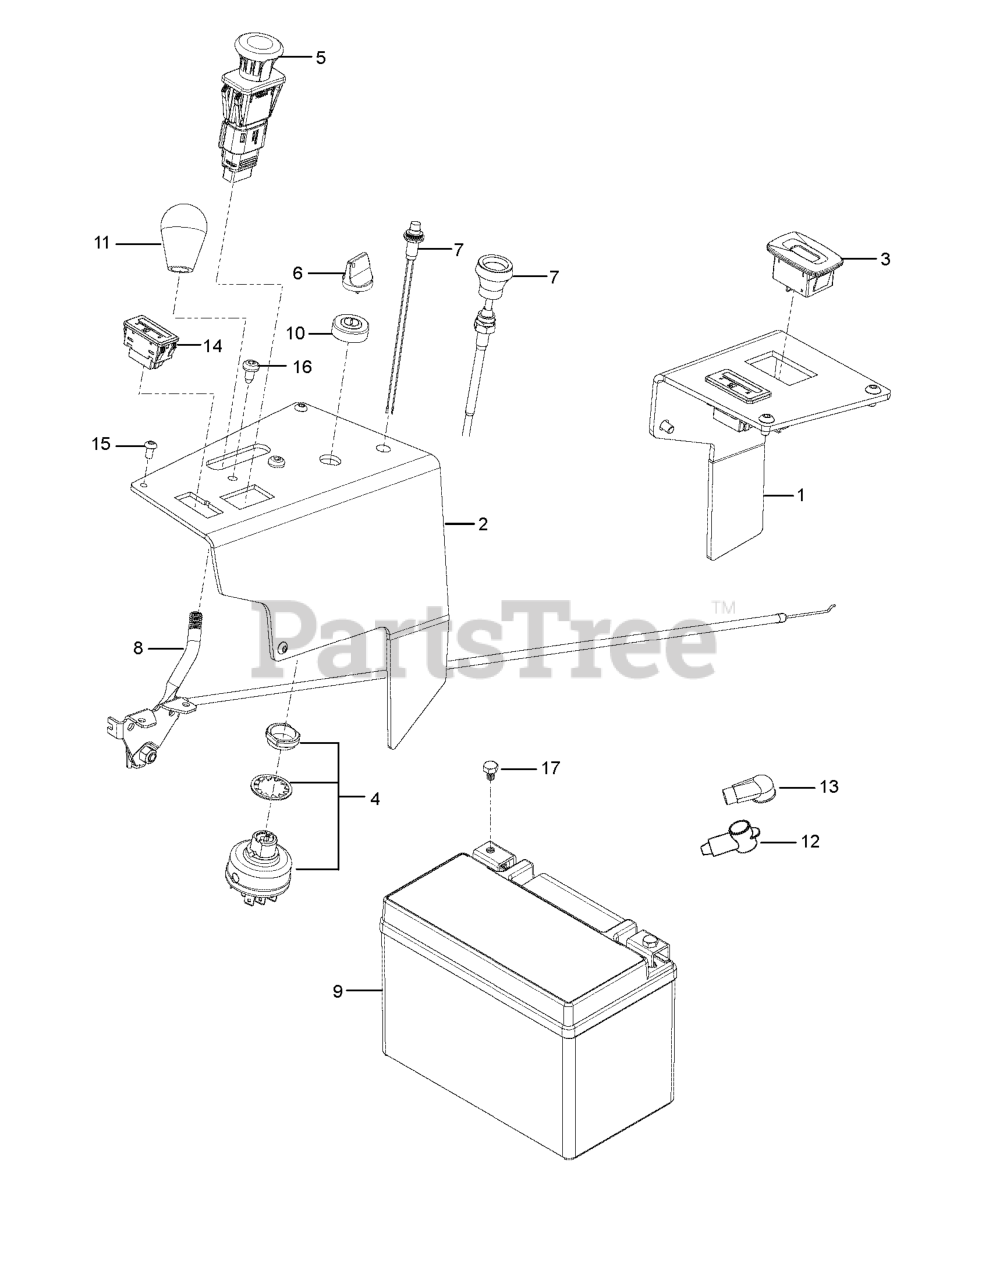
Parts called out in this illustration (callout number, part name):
1	PANEL.LH.CONTROL.PNT.X498
2	PANEL.RH.CONTROL.PNT.X498
3	GUAGE.SRVCMNDR.HRMTR.
4	SWITCH, IGNITION, INDAK
5	SWITCH.PTO.10AMP.SEALED.6P.SPS
6	KEY, IGNITION
7	CABLE, CHOKE, 48"
7	LED.LIGHT.SERVICE.EFI
8	THROTTLE.CONTROL.POST.MZ/PZ.46
8	THROTTLE.CONTROL.POST.PZ/MZ.60
9	BATTERY.STARTER.AGM.LEOCH.8AH
9	Batteries
9	Brackets
10	CAP IGNITION NUT
11	KNOB - SHIFT
13	BATTERY.CABLE.BOOT.RED.MZ.PZ.E
14	FUEL.GAUGE.LED.LEVEL.Z500
15	SCR #10-24 X 3/8 SKT HD BLK OX
16	SCREW T-30 1/4-20 X
17	SCREW M6 X 8MM HEX CAP
